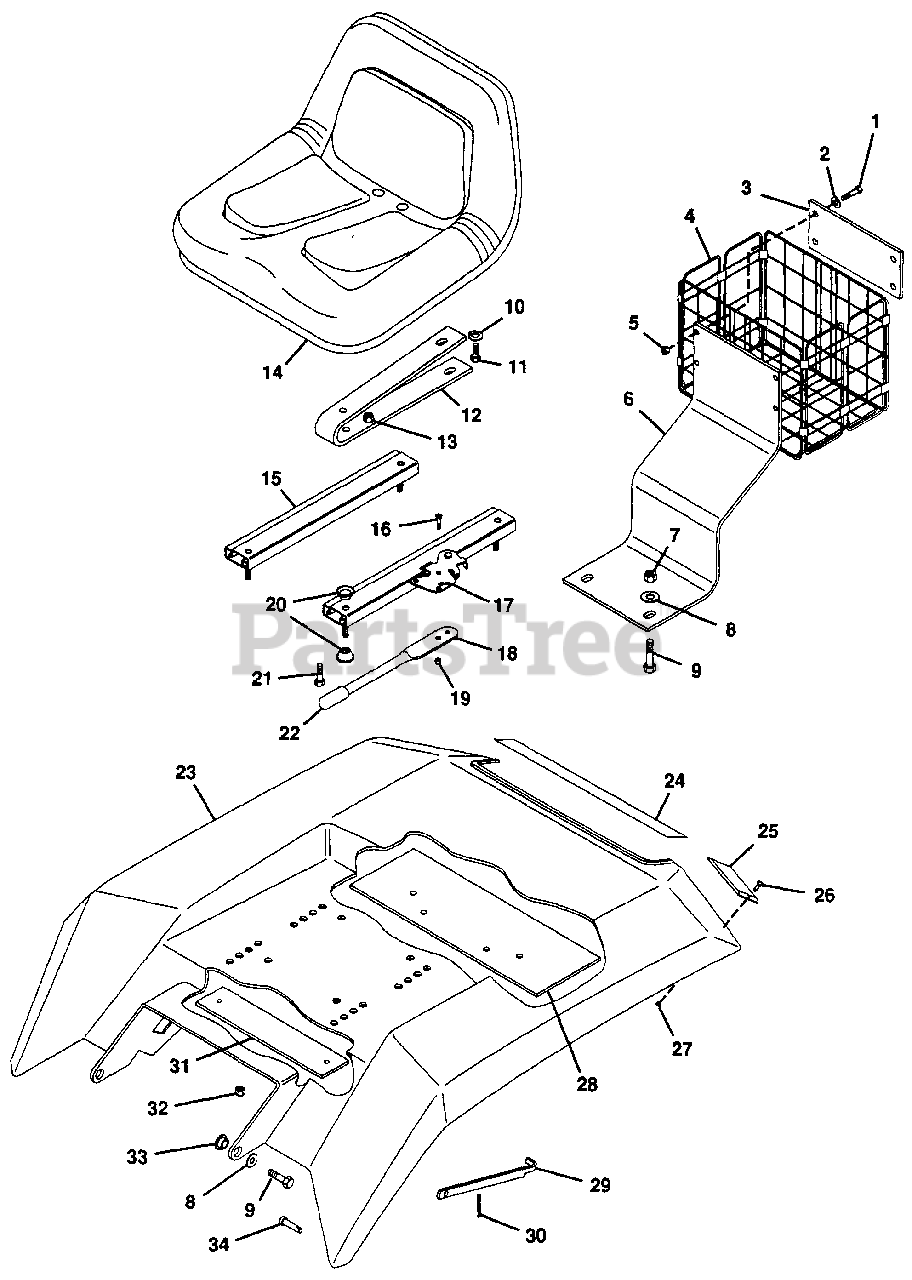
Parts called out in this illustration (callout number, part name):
1	BOLT, HEX 1/4-20X1.00
2	WASHER, FLAT .281X.625X.065
3	STRAP, BASKET
4	BASKET
5	NUT, LOCK 1/4-20 SER. FLG.
6	BRACKET, BASKET
7	NUT, LOCK 3/8-16
8	WASHER, FLAT .406X.812X.065
9	BOLT, HEX 3/8-16X1.00
10	WASHER, LOCK 5/16 REG.
11	BOLT, HEX 5/16-18X.75
12	SPRING, SEAT
13	NUT, LOCK 5/16-18
14	SEAT, HIGH BACK
15	ADJUSTER, SEAT
16	SCREW, MACHINE 10-24X.625 PHD
17	ADJUSTER, SEAT W/LATCH
18	HANDLE, SEAT SLIDE
19	NUT, LOCK 10-24
20	BUSH,. FLG. .375X1.16X.320 STL.
21	BOLT, HEX 5/16-18X1.25
22	TIP, LEVER
23	WELDMENT, SEAT PAN NOTCHED
24	DECAL, GRAVELY LOGO
25	REFLECTOR, RECT. REFLEX.
26	SCREW, MACHINE 10-31X.50 PHD
27	NUT, LOCK 10-32
28	BRACKET, SEAT SUPPORT
29	STRAP, FENDER HOLD-UP
30	PIN, COTTER .06X.75
31	BRACKET, SEAT
32	NUT, LOCK 5/16-18
33	BUSH., FLG. .406X.880X.270 BRZ.
34	PIN, CLEVIS .250X.406
